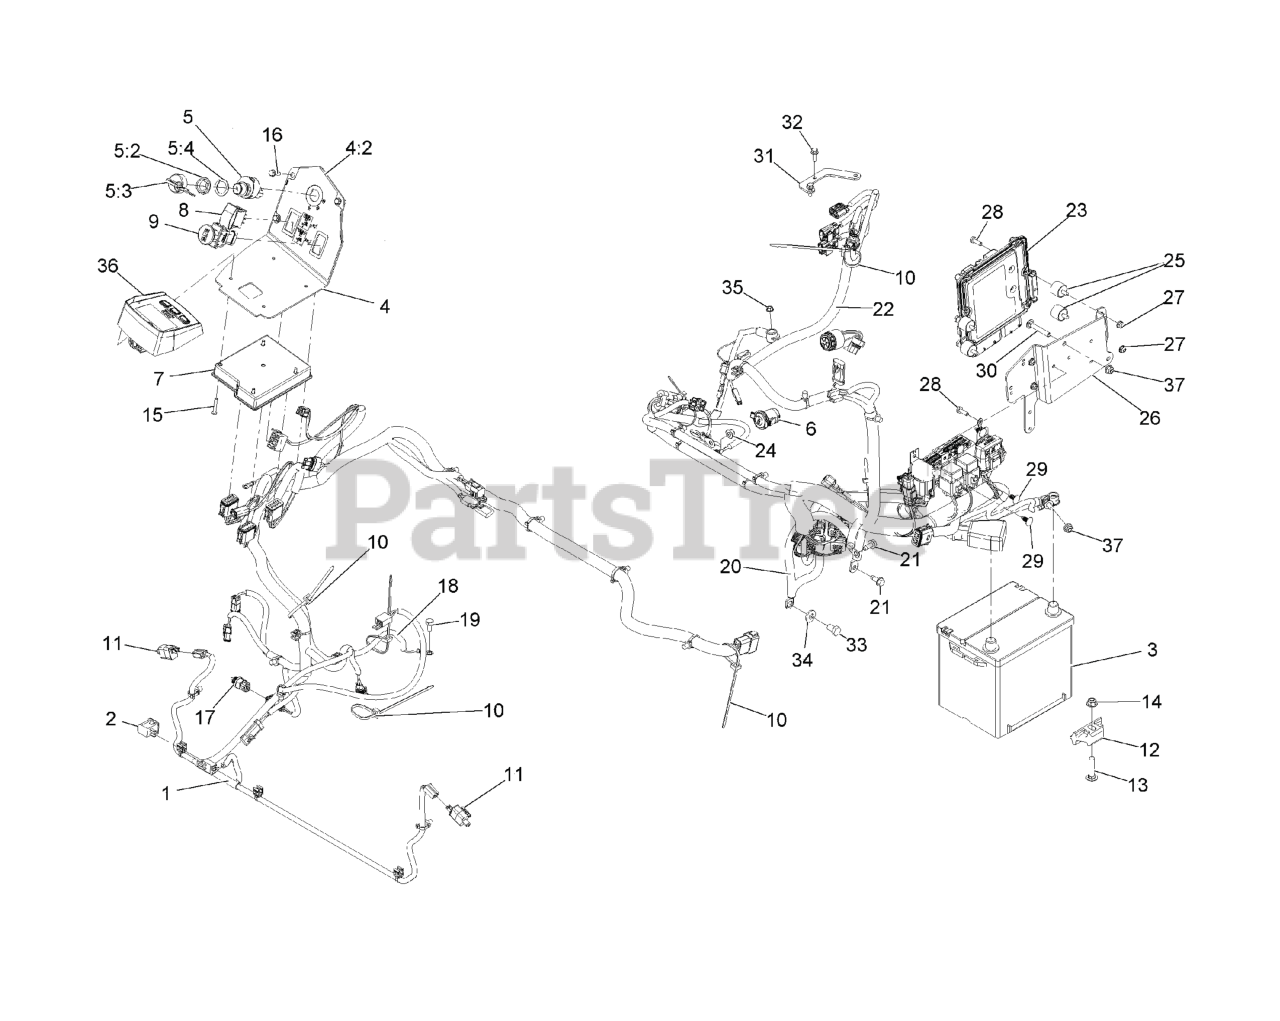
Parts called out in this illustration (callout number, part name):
1	HARNESS-WIRE
2	SWITCH-BAIL
3	Battery-Dry
4	Console ASM
4:2	DECAL-CONSOLE
5	IGNITION SWITCH ASM
5:2	NUT-MOUNTING
5:3	IGNITION KEY SET
5:4	WASHER-BACKUP
6	PORT-POWER, 12V
7	Module-Mcu
9	SWITCH-PTO, SEALED
10	TIE-CABLE
12	RETAINER-BATTERY
13	SCREW-CARR
14	NUT-HF, NI
15	SCREW-PPH
16	SCREW-HWH
17	SENSOR-TEMPERATURE
18	HARNESS-WIRE, JUMPER
19	BOLT
20	CABLE-BATTERY
21	Screw-HWH 5/16-18 X 3/4 Tf
22	HARNESS-WIRE
23	Electronic Control Unit
25	MOUNT-CYLINDRICAL
26	MOUNT-CONTROL UNIT, ENGIN
28	SCREW-HH
29	PLUG-PLASTIC
30	BOLT-CARR
31	BRACKET-WIRING, ENGINE
32	SCREW-HHF
33	SCREW-HH
34	WASHER-BELLEVILLE
36	MODULE, LDU
37	NUT-HF, NI
